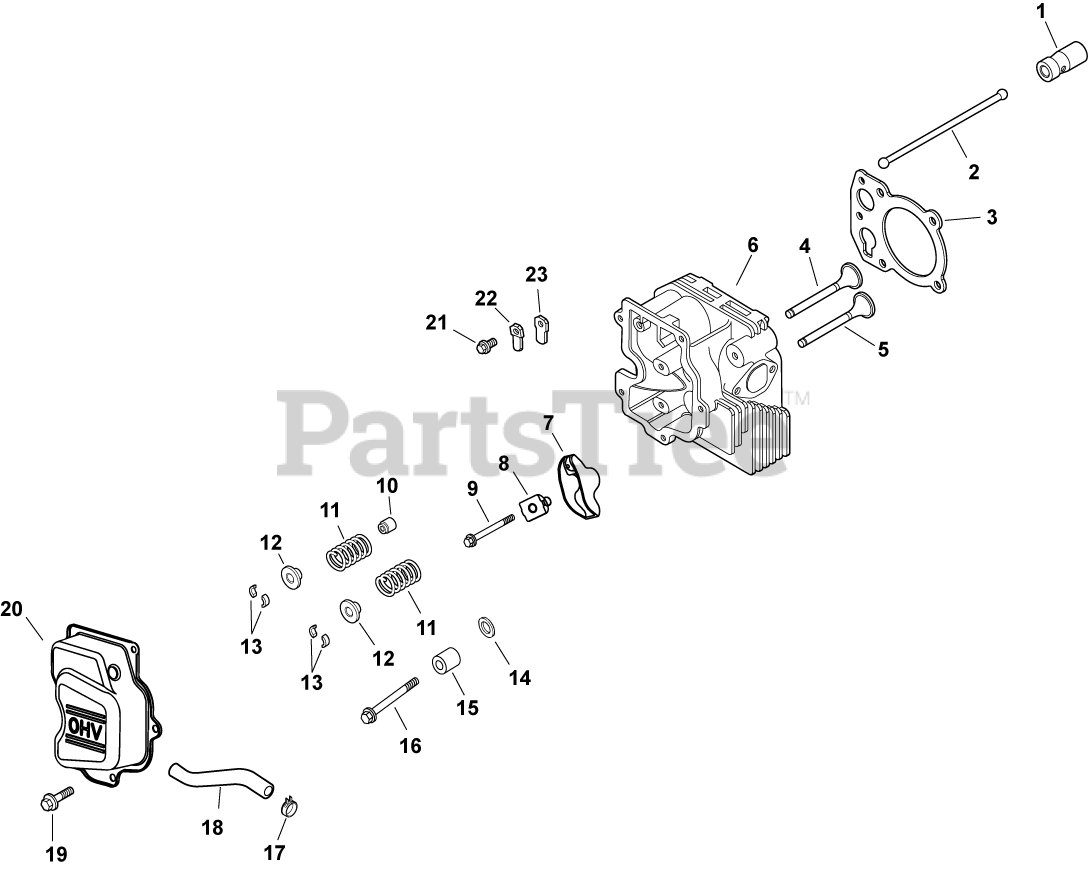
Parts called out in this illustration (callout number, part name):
1	LIFTER, HYDRAULIC VALVE-USE 25 351 10-S
2	ROD, PUSH
3	GASKET, CYLINDER HEAD
4	VALVE, INTAKE
5	VALVE, EXHAUST
6	HEAD ASSEMBLY, CYLINDER
7	ARM, ROCKER
8	PIVOT, ROCKER ARM
9	SCREW, FLG M6X1.0X34
10	SEAL, VALVE STEM - (#2503214S)
11	SPRING, VALVE
12	RETAINER, VALVE SPRING - USE 25 173 28-S
13	KIT, RETAINER
14	WASHER, FLAT 13/32"
15	SPACER, HEAD BOLT EXHAUST PORT
16	SCREW, CYLINDER HEAD (M10 X 80)
17	CLAMP, HOSE (KM)-USE 25 237 31-S
18	HOSE
19	SCREW,FLG THD FRM M6X1.0X16-(#25086397S)
20	COVER, ROCKER
21	SCREW, FLG THD FRM M5X.8X10
22	RETAINER, REED
23	REED, BREATHER
1232630-S	HOSE, BREATHER
